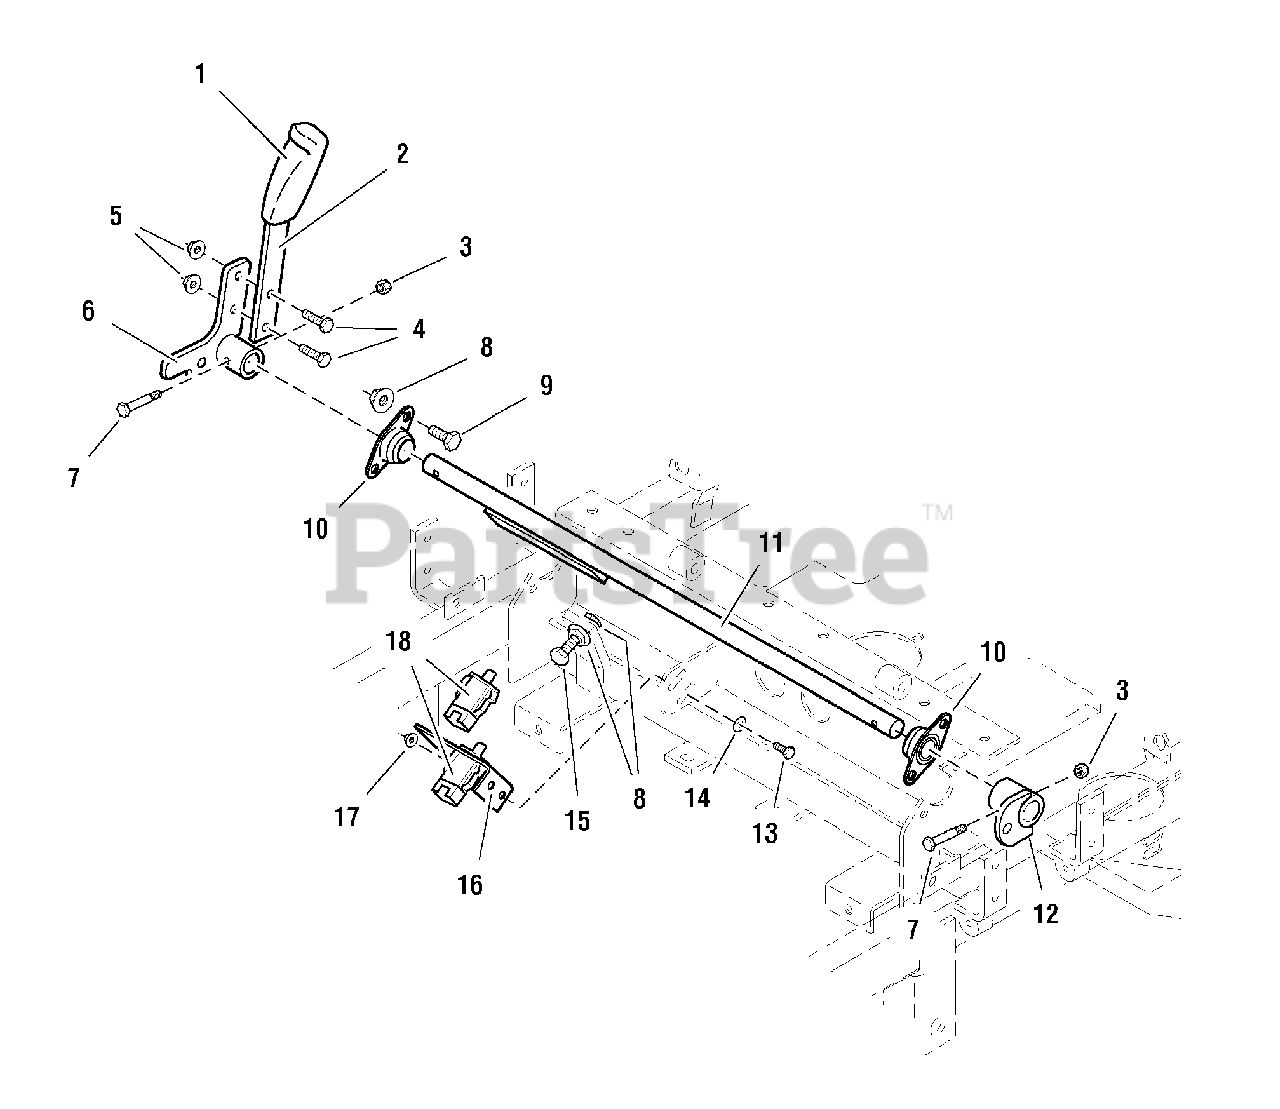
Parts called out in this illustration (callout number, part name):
2	BRAKE HANDLE
3	NUT, Hex, Nylon Lock, 1/4-20
4	CAPSCREW, Hex Hd, 5/16-18 x 1
5	NUT, Hex, Serrated Flange, 5/16-18
6	BRAKE HANDLE MOUNT
7	CAPSCREW, Hex Hd, 1/4-20 x 1-3/4
8	NUT, Hex, Serrated Flange, 3/8-16
9	CAPSCREW, Hex Hd, 3/8-16 x 3/4
10	BEARING, Flange
11	BRAKE HANDLE SHAFT
12	BRAKE LINKAGE PIVOT
13	CAPSCREW, Hex Hd, 1/4-20 x 3/4
14	WASHER, 1/4 SAE (5025154)
15	CAPSCREW, Hex Hd, 3/8-16 x 1-3/4 TFL
16	SWITCH MOUNT BRACKET
17	NUT, Hex, Serrated Flange, 1/4-20
18	SWITCH
